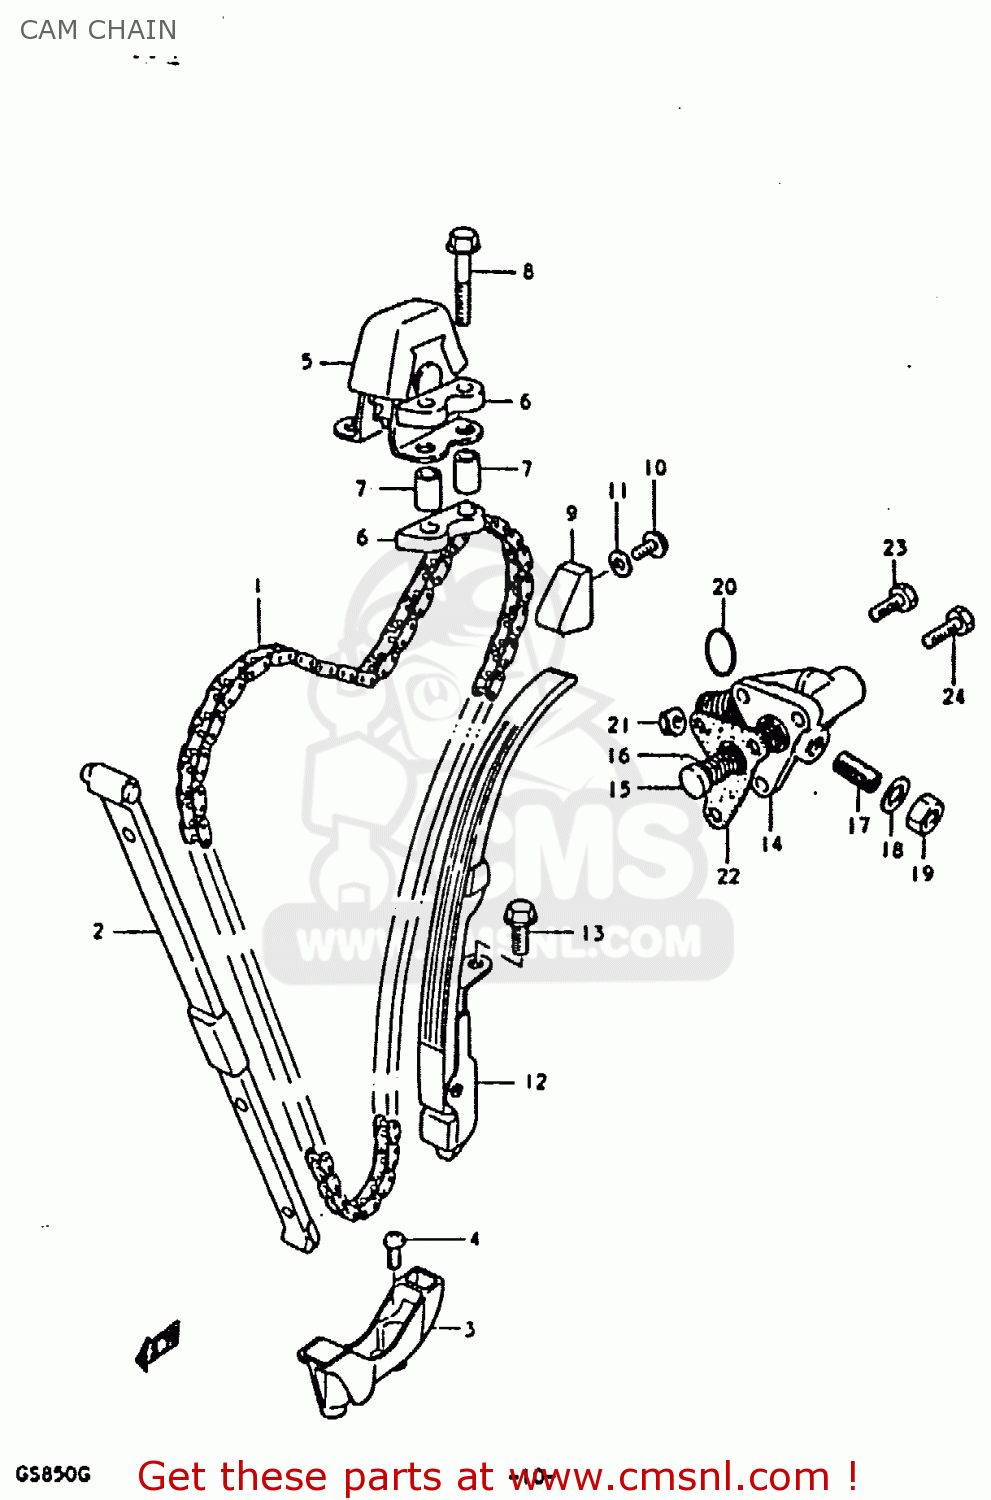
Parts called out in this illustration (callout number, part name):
1	CHAIN,CAMSHAFT DRIVE(120L)
2	GUIDE,CAM CHAIN
3	HOLDER,CAM CHAIN GUIDE
4	SCREW
5	IDLER,CAM CHAIN
6	CUSHION,IDLER
7	SPACER
8	BOLT
9	GUIDE,CAM CHAIN
10	BOLT
11	GASKET (NAS)
12	TENSIONER,CAM CHAIN
13	BOLT
14	ADJUSTER ASSEMBLY,TENSIONER
15	ROD,PUSH
16	SPRING
17	SCREW
18	WASHER
19	NUT
20	O-RING
21	NUT
22	GASKET,TENSIONER ADJUSTER (MCA)
23	SCREW
24	SCREW
